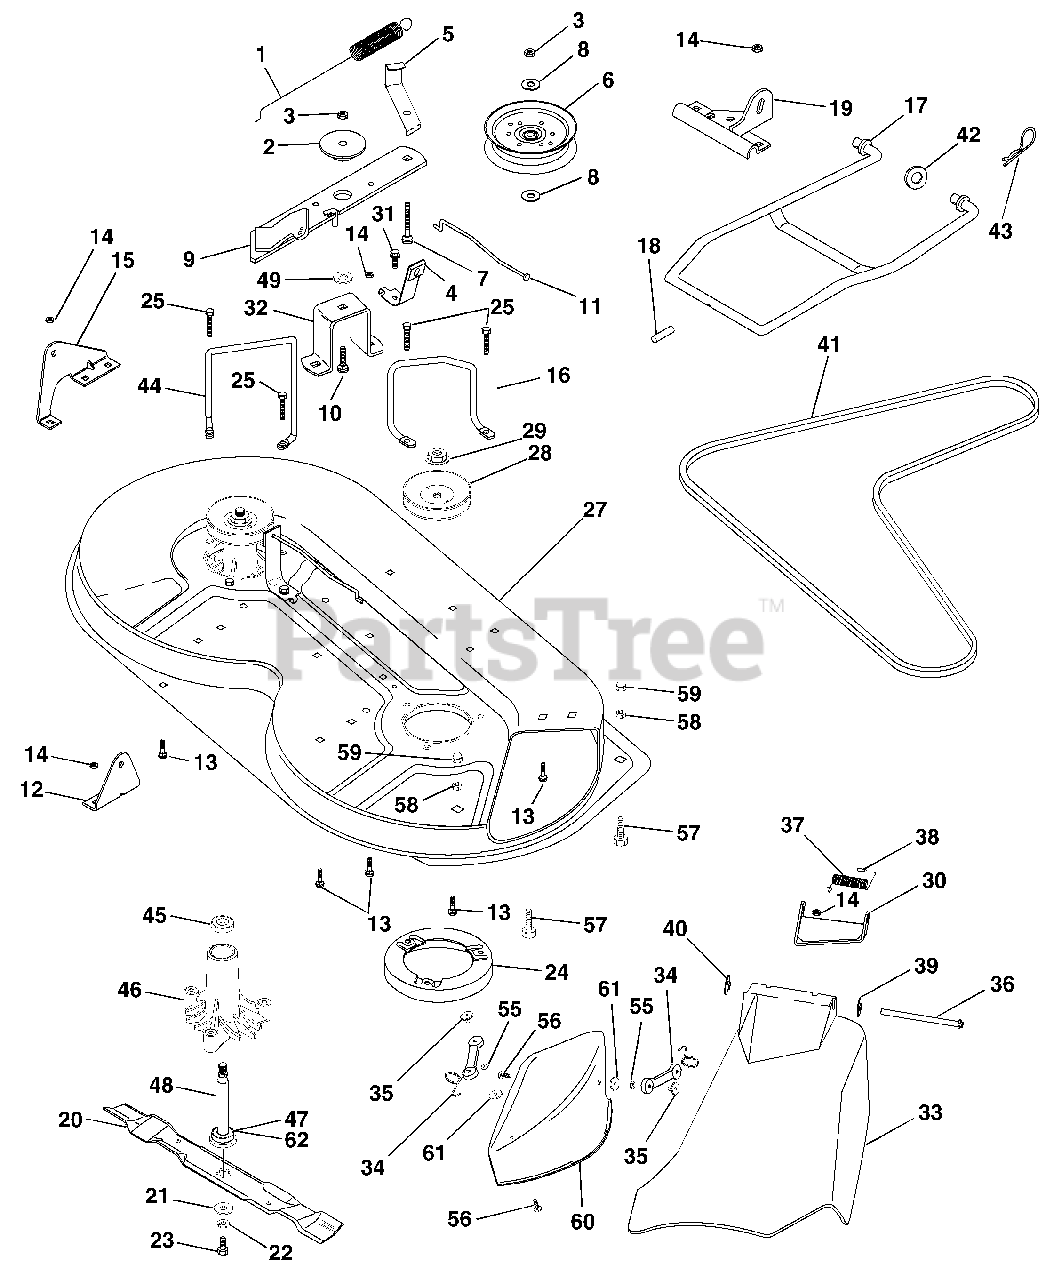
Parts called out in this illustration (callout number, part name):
1	Spring, Mower Clutch
2	Spacer, Retainer
3	Nut, Crownlock 3/8-16
4	Brake Asm.
5	Guide, Belt Idler
6	Pulley, Flat Idler
7	Bolt, Carr. 3/8-16 x 1-3/4 Gr. 5
8	Washer 13/21 x 7/8 x 10 Ga.
9	Arm Asm., Idler Mower
10	Bolt, Carriage 3/8-16 x 1-1/4
11	Rod, Brake
12	Bracket, Lift R. H. Rear
13	Bolt, Carriage 5/16-18 x 3/4
14	Nut, Crownlock 5/16-18
15	Bracket, Lift L. H. Rear
16	Keeper, R. H.
17	Link, Asm. Mower Stabilizer
18	Pin, Drive
19	Bracket, Asm. Front
20	Blade Mulching
21	Washer, Hard
22	Washer, Lock 3/8
23	Bolt 3/8-24 x 1-1/4 Gr. 8
24	Stripper
25	Screw Thdrol Hex Hd
27	Deck Assembly
28	Pulley, Mandrel
29	Nut, Flangelock 9/16
30	Bracket, Asm. Deflector
31	Screw, Hex Wsh. Thdrol. 5/16-18 x 1/2
32	Arm, Support Idler Mower
33	Deflector
34	Latch Asm, Bagger
35	Nut, Weld
36	Rod, Hinge
37	Spring, Torsion Deflector
38	Cap, Sleeve
39	Washer 11/32 x 5/8 x 16 Ga.
42	Washer 11/32 x 5/8 16 Ga.
43	Retainer, Spring
44	Keeper, L. H.
46	Housing Mandrel Vented
48	Shaft, Mandrel
49	Washer, Hardened
55	Washer, Lock
56	Screw
57	Bolt, Fin Hex 5/16-18 x 1
58	Nut, Nylon Insert
59	Nut, Acorn Hex 5/16 x 18
60	Cover, Mulching
62	Washer Felt
